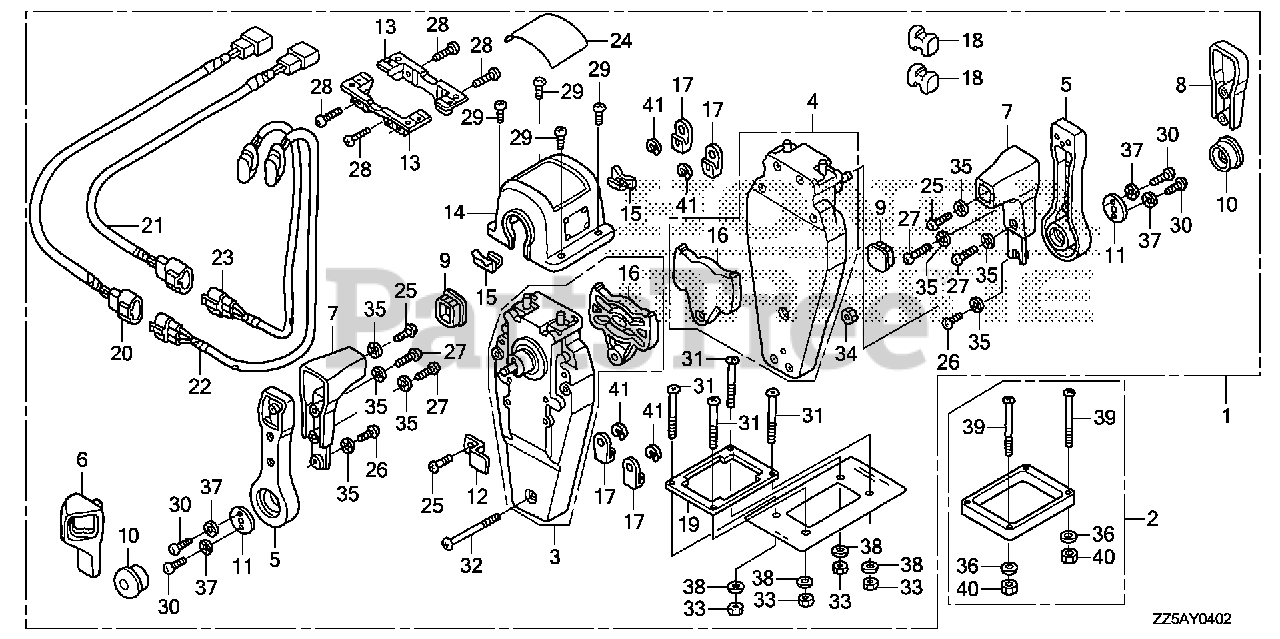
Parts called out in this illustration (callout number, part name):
1	BOX KIT, REMOTE CONTROL (TOP MOUNT DUAL)(R)
2	SPACER KIT, REMOTE CONTROL BOX (TOP MOUNT DUAL)
3	HOUSING ASSY., L. (INNER) (TOP MOUNT)
4	HOUSING ASSY., R. (INNER) (TOP MOUNT)
5	HANDLE, REMOTE CONTROL
6	COVER, L. GRIP
7	GRIP, REMOTE CONTROL HANDLE
8	COVER, DUAL GRIP
9	CAP, GRIP
10	BUTTON, THROTTLE
11	PLATE, HANDLE
12	PLATE, CABLE CLAMP
13	BRACKET, REMOTE CONTROL HOUSING
14	HOUSING, DUAL REMOTE CONTROL BOX
15	HOUSING, LEAD
16	PLATE, DWELL
17	TERMINAL, CABLE
18	SPACER, CABLE CLAMP
19	GASKET, DUAL
20	SUB-HARNESS ASSY., POWER TRIM-TILT (A)
21	SUB-HARNESS ASSY., POWER TRIM-TILT (B)
22	SWITCH ASSY., POWER TRIM-TILT (A)
23	SWITCH ASSY., POWER TRIM-TILT (B)
24	MARK, REMOTE CONTROL (DUAL)
25	SCREW, PAN (5X16)
26	SCREW, PAN (5X10)
27	SCREW, PAN (5X20)
28	SCREW, PAN (5X18)
29	SCREW, PAN (4X10)
30	SCREW, PAN (6X18)
31	SCREW, PAN (5X40)
32	SCREW, PAN (5X55)
33	NUT, HEX. (5MM)
34	NUT, HEX. (5MM)
35	WASHER, LOCK (5MM)
36	WASHER, PLAIN (5MM)
37	WASHER, LOCK (6MM)
38	WASHER, PLAIN (5MM)
39	SCREW, PAN (5X65)
40	NUT, HEX. (5MM)
41	E-RING (6MM)
